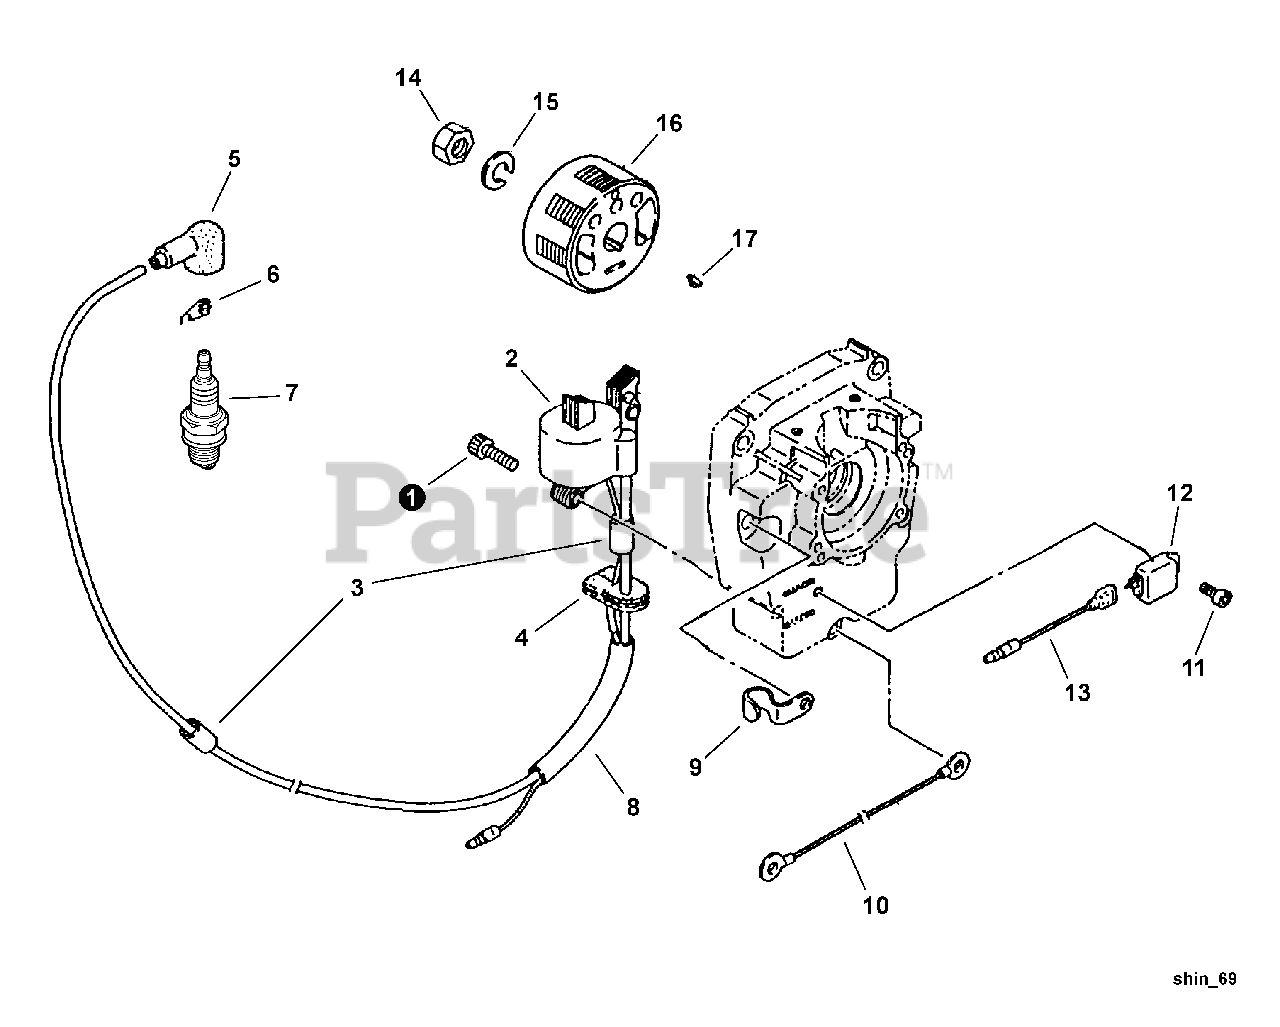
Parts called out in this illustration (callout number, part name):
1	BOLT M5×20
2	COIL, IGNITION
3	SUPPORT, PIPE
4	GROMMET
5	CAP, SPARK PLUG
6	TERMINAL, SPARK PLUG
8	TUBE
9	CLIP
10	LEAD - GROUND
11	BOLT M4×10
12	UNIT
13	LEAD - IGNITION
14	NUT 10×1.25
15	WASHER, SPRING 10
16	FLYWHEEL
17	KEY, WOODRUFF 3×10
